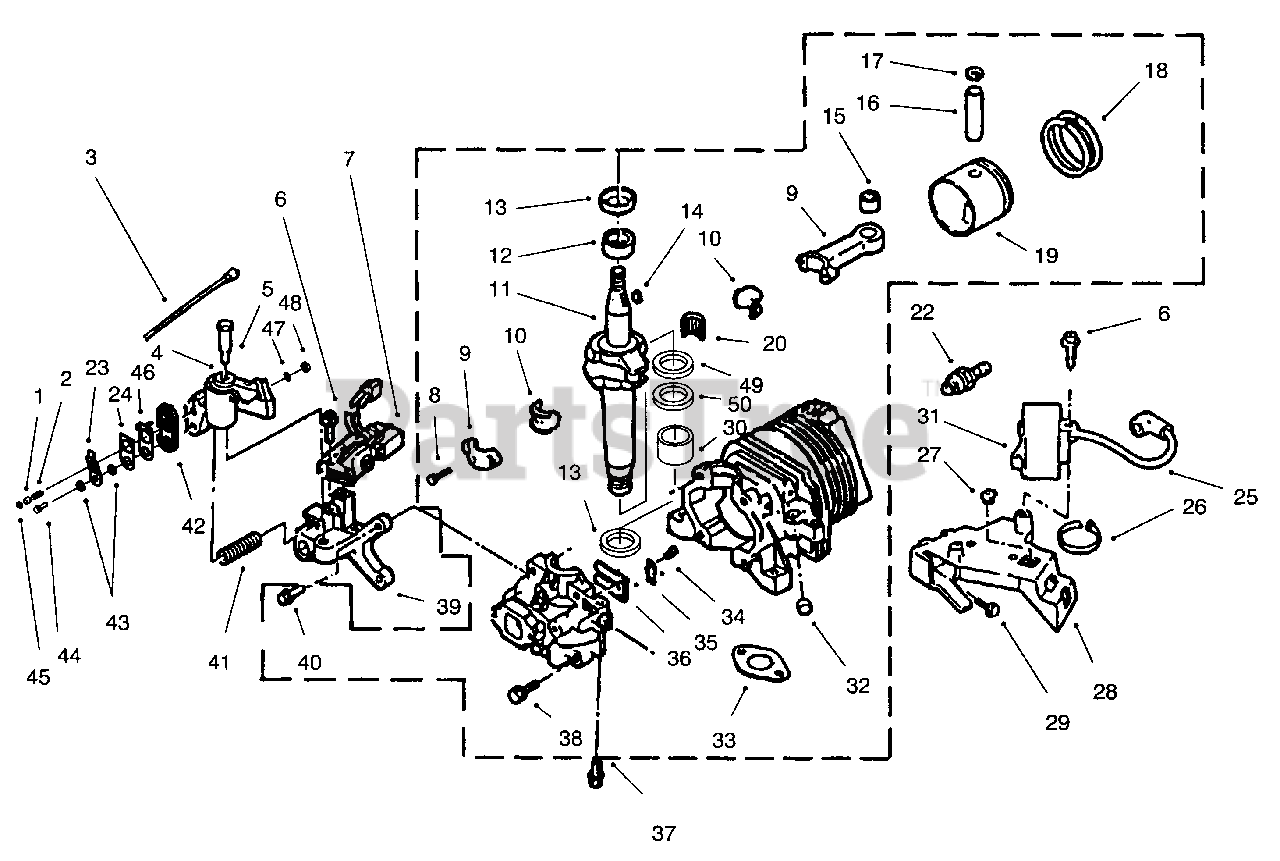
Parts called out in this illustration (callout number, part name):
1	Actuator-Brake Lever
2	Spring-Cable Return
4	Brake Assembly
5	Bolt-Shoulder
6	Screw-C.D. Mounting
7	Alternator Assembly
8	Screw-Cap
9	Connecting Rod Assembly (Incl. Ref. #8, 10, & 20)
10	Liner-Split (1 pair)
11	Crankshaft
12	Bearing-Upper Main
13	Seal-Upper Oil
14	Key-Flywheel
15	Bearing Assembly
16	Pin-Wrist
17	Ring-Retaining
18	Ring Set
19	Piston & Ring Set (Incl. Ref. #16-18)
20	Strip-Roller
22	Plug-Spark
23	Spring-Contact
25	Lead-High Tension
26	Strap-Tie
27	Grommet
28	Bracket-C.D. Mounting
30	Bearing
31	Module-C.D. Ignition & Lead
33	Gasket-Exhaust
34	Screw-Reed To Cover
35	Plate-Reed Hold Down
37	Screw-Set
38	Screw-Cover to e
39	Bracket
40	Screw-Brake Mtg. Brkt.
41	Spring-Brake
42	Case Assembly
43	Washer
44	Screw-Hex Hd. Cap
45	Retainer
46	Plate-Contact
47	Washer-Ext. Tooth Lock
48	Nut
49	Bearing-Thrust
50	Washer-Thrust
